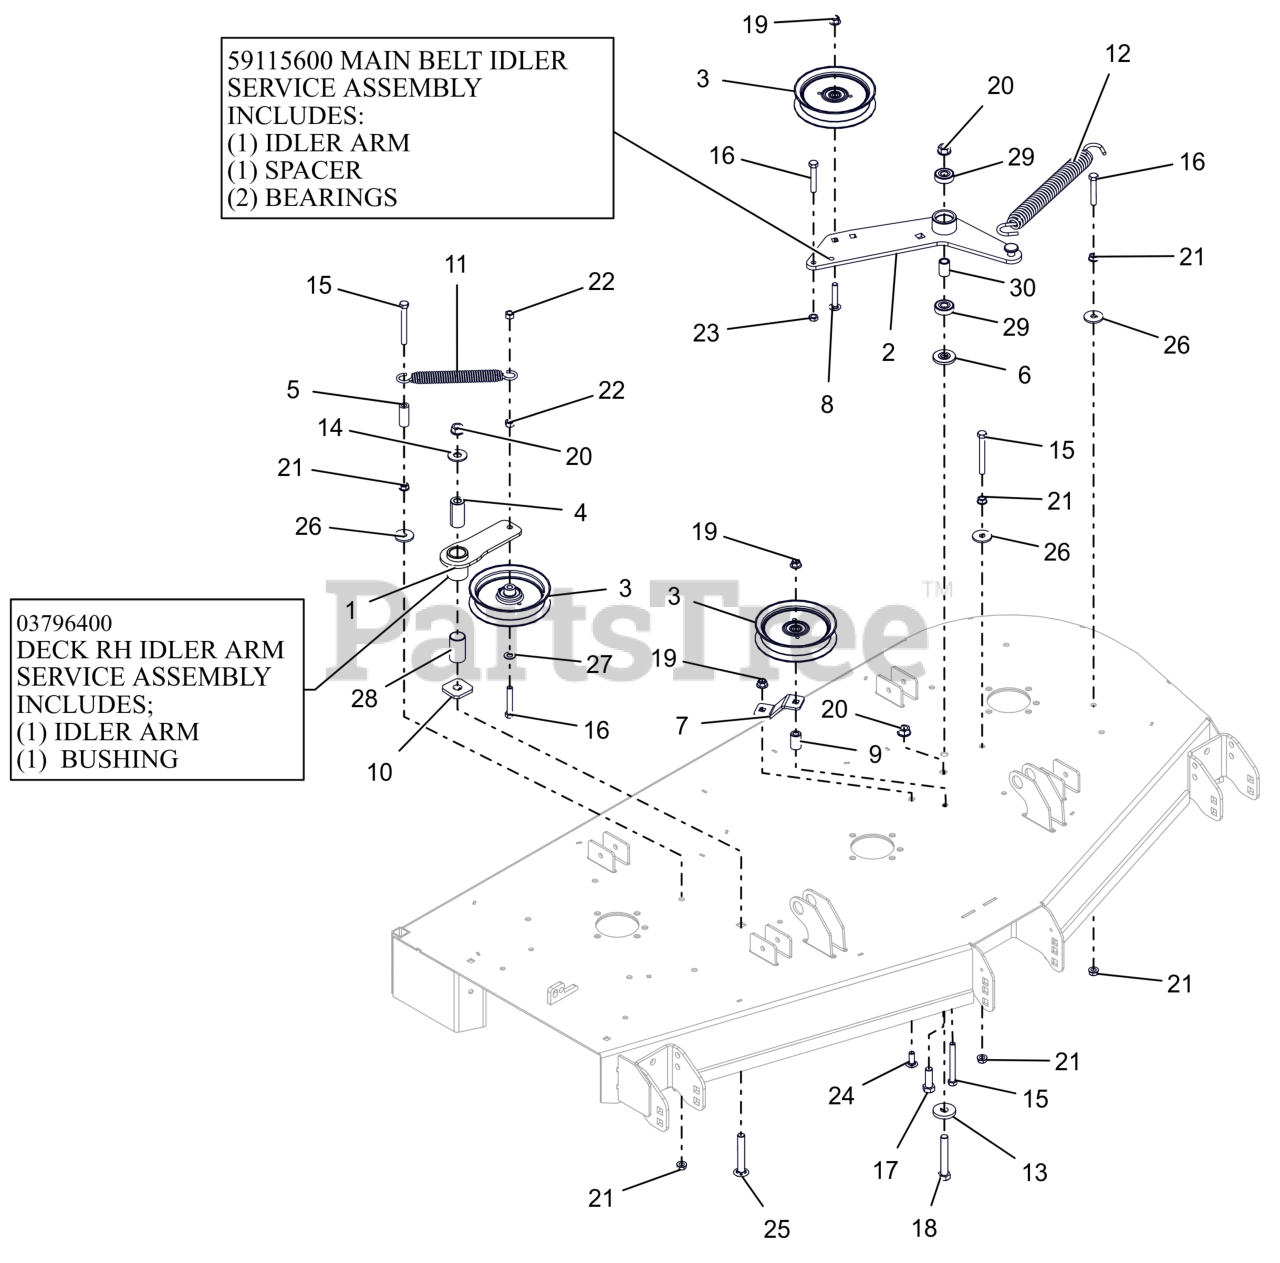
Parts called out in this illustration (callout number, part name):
1	WMT, IDLER ARM - BLACK
1	ASM, IDLER ARM (DECK)
2	WLDMT, DECK PTO IDLR ARM
2	ASSEMBLY, MAIN BELT IDLER
3	IDLER, FLAT 5.00"
4	BSHG, SPCR .502X.997X2.03 PM
5	HOSE, .38 X 1.65
6	SPACER, IDLER ARM
7	PTO FIXED IDLER MTG BRKT-ORG
8	BLT,RHSSN.375-16X2.00 G5 ZCC
9	BUSHING, SLV .380X.750X1.190
10	WSHR-FLT .640X1.75X.250
11	SPRING, EXTENSION
12	SPRING, EXTENSION
13	WSHR-FL-STL 0.557X1.625X0.25 ZCC
14	WSHR,FLT .563X1.375X.109 ZCC
15	BLT, HEX .38-16X3.25 G5 ZCC
16	BLT,HEX .38-16X2.25 G5 ZCC
17	BLT,HEX .50-13X1.50 G5 ZCC
18	BLT,HEX .50-13X3.25 G5 ZCC
19	NUT,NYL-FLG .38-16 GF ZCC
20	NUT-LK-CTR-FLG .500-13 GG ZCC
21	NUT, SPNLK-FLG .38-16 G5 ZCC
22	NUT-LK-CTR .38-16 ZC120
23	NUT-JAM .375-16 G2 ZCC
24	BLT,RHSSN .38-16X1.00 G5 ZCC
25	BTL,RHSSN .500-13 X 3.25 G5 ZCC
26	WSHR,FLT .406X1.375X.135 ZCC
27	WSHR,FLT .406X.812X.065 ZCC
28	BSHG, 1.00X1.125X1.937
29	BRG-BALL .500X1.38X.437
30	SPACER .510 X .75 X 1.1485
